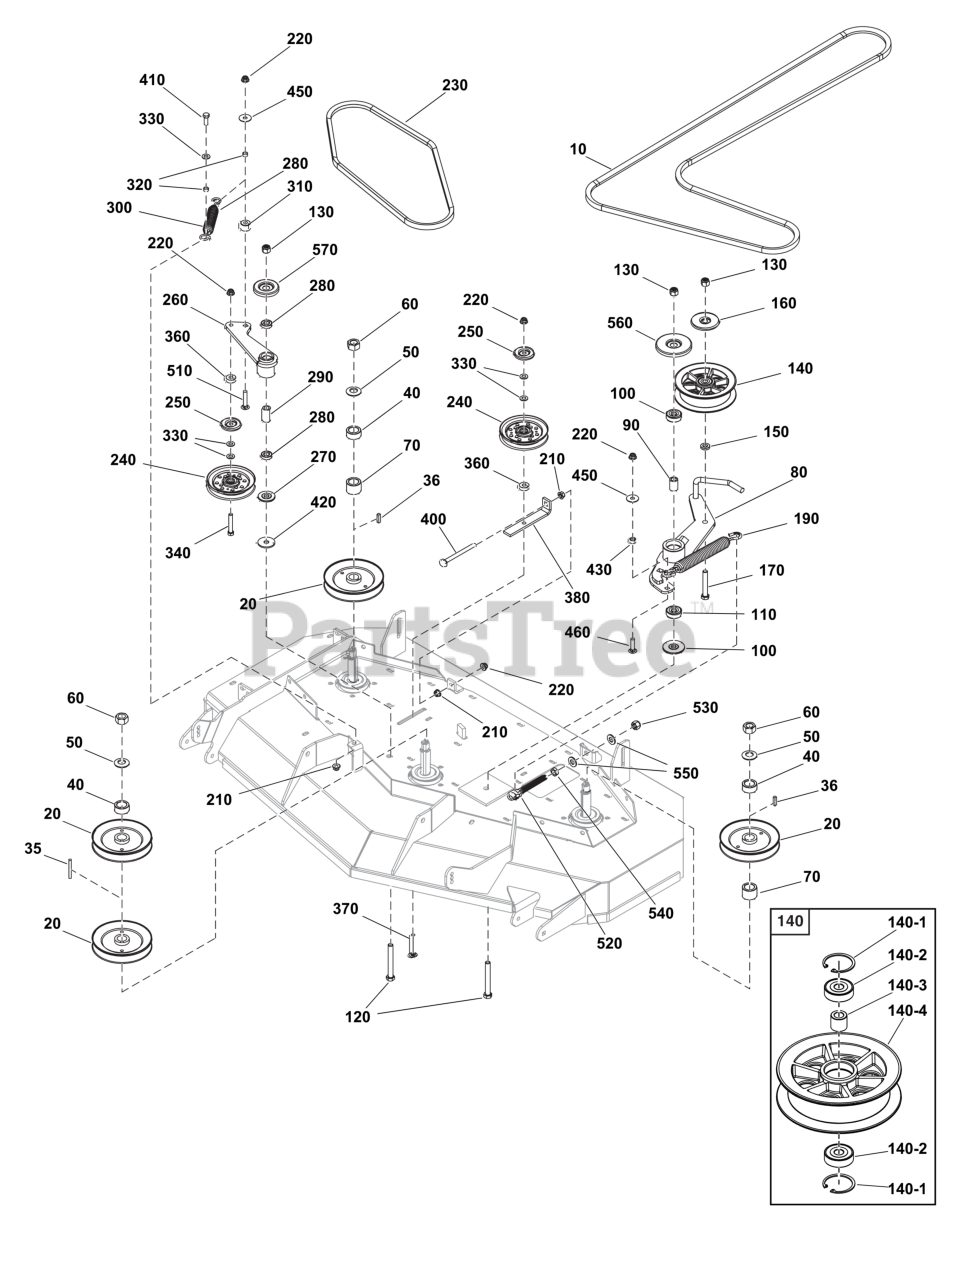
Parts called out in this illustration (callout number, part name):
35	KEY - 1/4 SQX2 1/4
36	KEY, 1/4" SQ. X 1.00
50	WASHER, Beveled
60	NUT, 3/4-16 HEX
80	ARM-IDLER
110	SPACER, .51 X .84 X 1
120	BOLT, 1/2-13 X 4 GD5
140	PULLEY ASSEMBLY
140-1	RING, SNAP
140-4	PULLEY HOUSING
150	SPACER .515X1.00X.218
170	BOLT, 1/2-13
210	NUT, 3/8-16 HEX SERRA
220	NUT, 3/8-16 HEX NYLOCK
260	ARM-IDLER
270	SPACER, IDLER ARM
280	BEARING, BALL, AXLE
290	SPACER, .52 X .84 X 1
300	SPRING, EXTENSION, SW
320	SPACER, .38 X .50 X .
340	BOLT, 3/8-16 X 2-3/4"
410	BOLT, 3/8-16 X 1" GD5
450	WASHER, 3/8" FENDER
510	BOLT, 3/8-16 X 2", CA
520	ANCHOR, SPRING
530	NUT, 1/2-20 HEX NYLON
540	NUT, 1/2-20 HEX JAM
550	WASHER, 1/2" SAE
560	SHIELD, BEARING, 1/2" ID-2.5"
570	SHIELD, BEARING, 1/2" ID-1.75"
